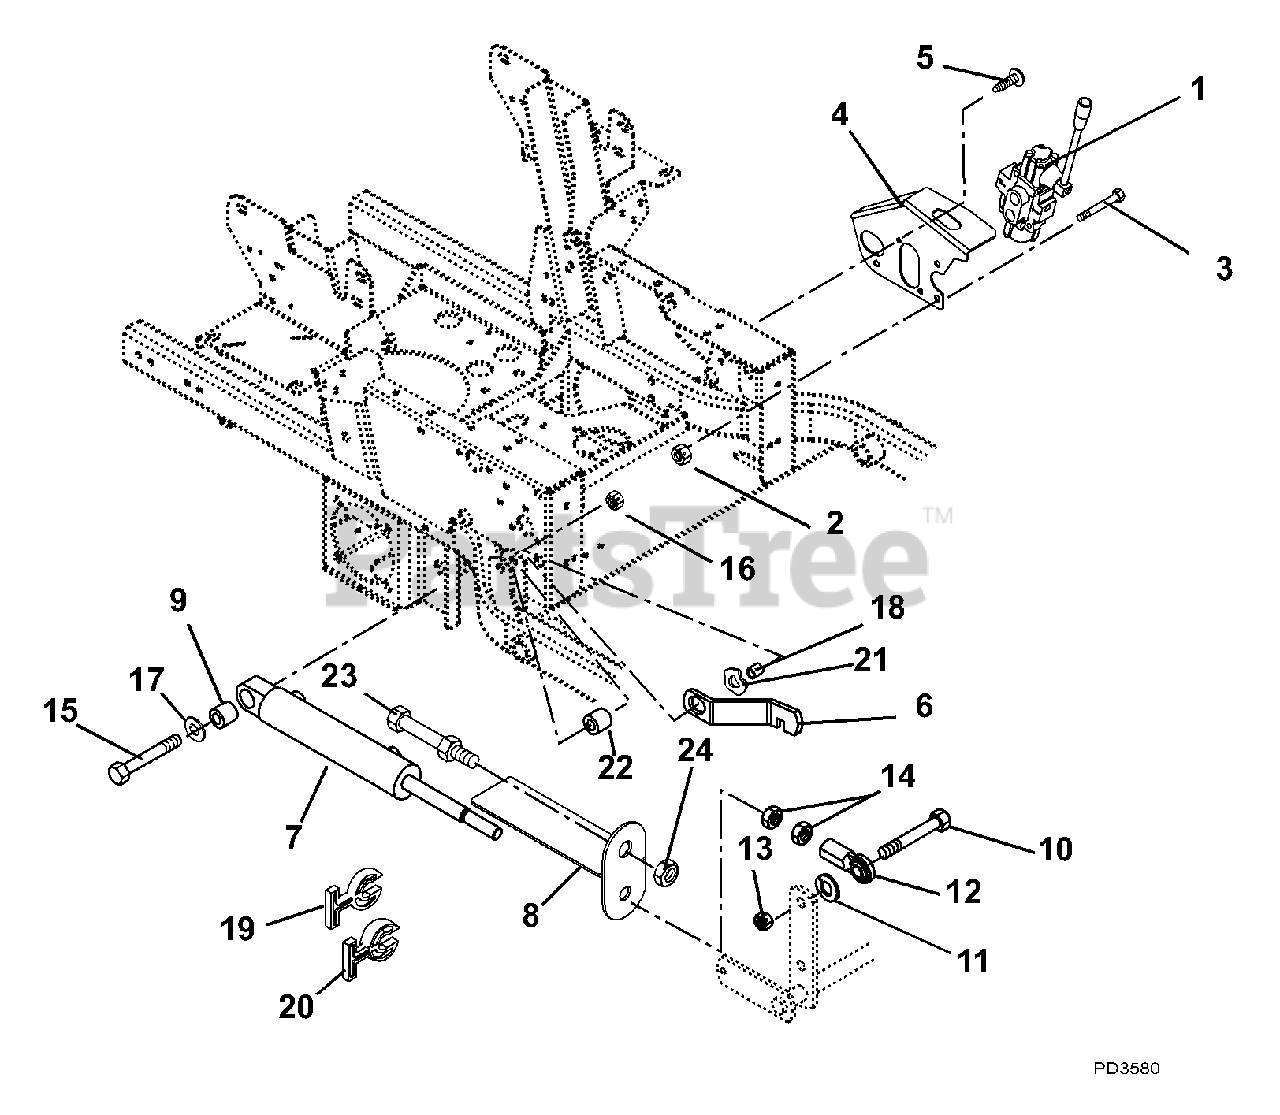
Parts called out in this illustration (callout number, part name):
1	Valve, Hydraulic
2	Nut, Locking Top Flange .31-18
3	Bolt, Hex .31-18 x 2.50 Grade 5
4	Valve Mounting Bracket
5	Screw, Tapping .38-16 x .50 Hex Washer Head
7	Cylinder, Lift
8	Strap, Cut Indicator/Guard
9	Bushing .516 x 1.00 x 1.050
10	Bolt, Hex .62-11 x 2.25 Grade 8
11	Washer, Lock .62 x .156
12	Rod End - Female - Right Hand .63
13	Nut, Locking Center .62-11
14	Nut, Jam .625-18
15	Bolt, Hex .50-13 x 3.50 Grade 5
16	Nut, Locking Top Flange .50-13
17	Washer, Flat Steel .515 x 1.625 x .25
18	Bushing, Flange .515 x .75 x .275 x 1.12
19	Stop, Cylinder .34 Thick
20	Stop, Cylinder .68 Thick
21	Washer, Wave .076 x 1.12 xz .08
22	Spacer .50 I.D. x .88 O.D. x .88
24	Nut-Jam .75-16
